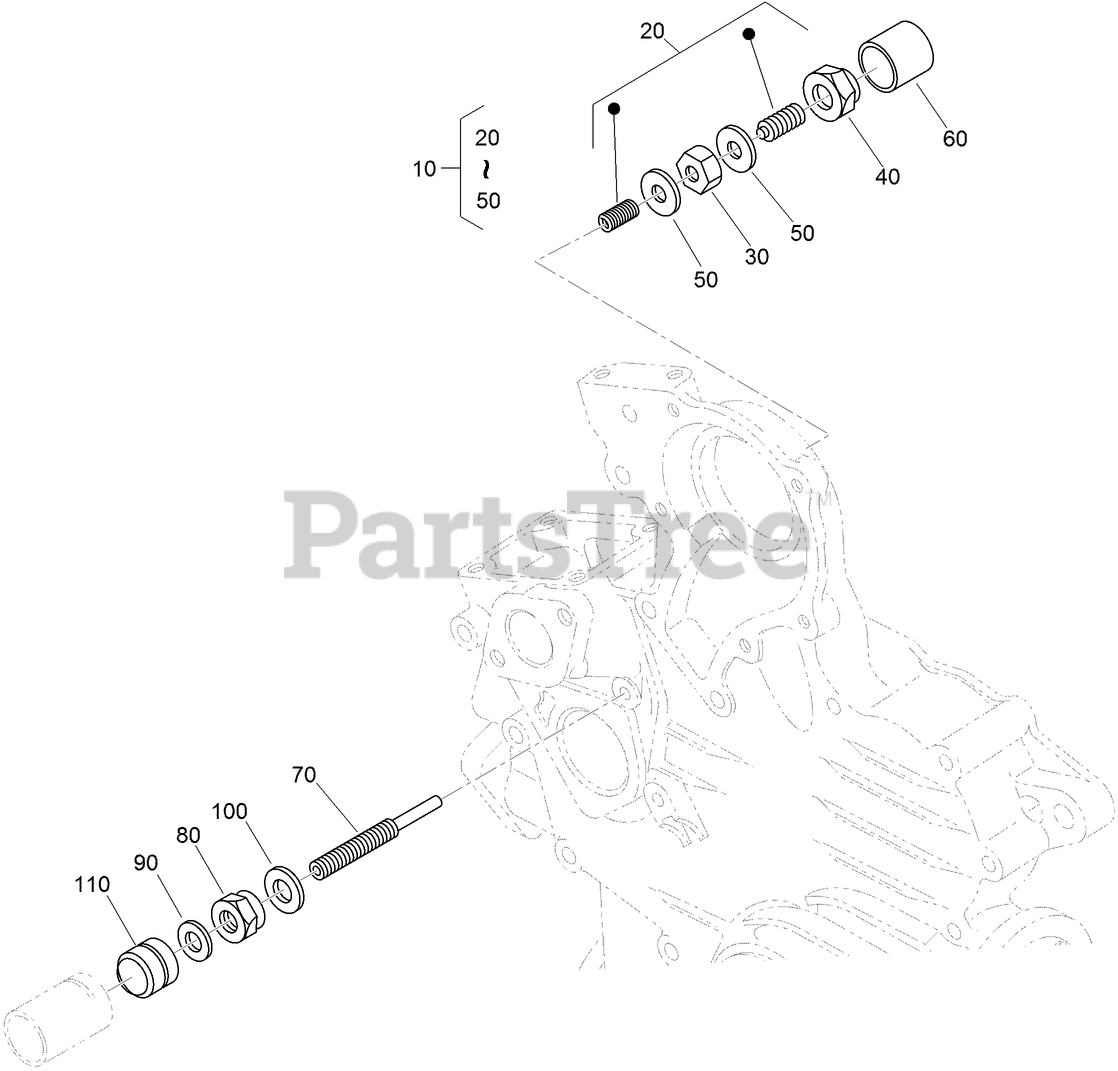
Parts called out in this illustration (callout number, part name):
10	IDLE APPARATUS ASM
20	ADJUSTING BOLT ASM
40	NUT-CAP
50	GASKET
70	BOLT-ADJUSTING
80	NUT-LOCK
90	GASKET
100	GASKET
110	NUT-CAP
